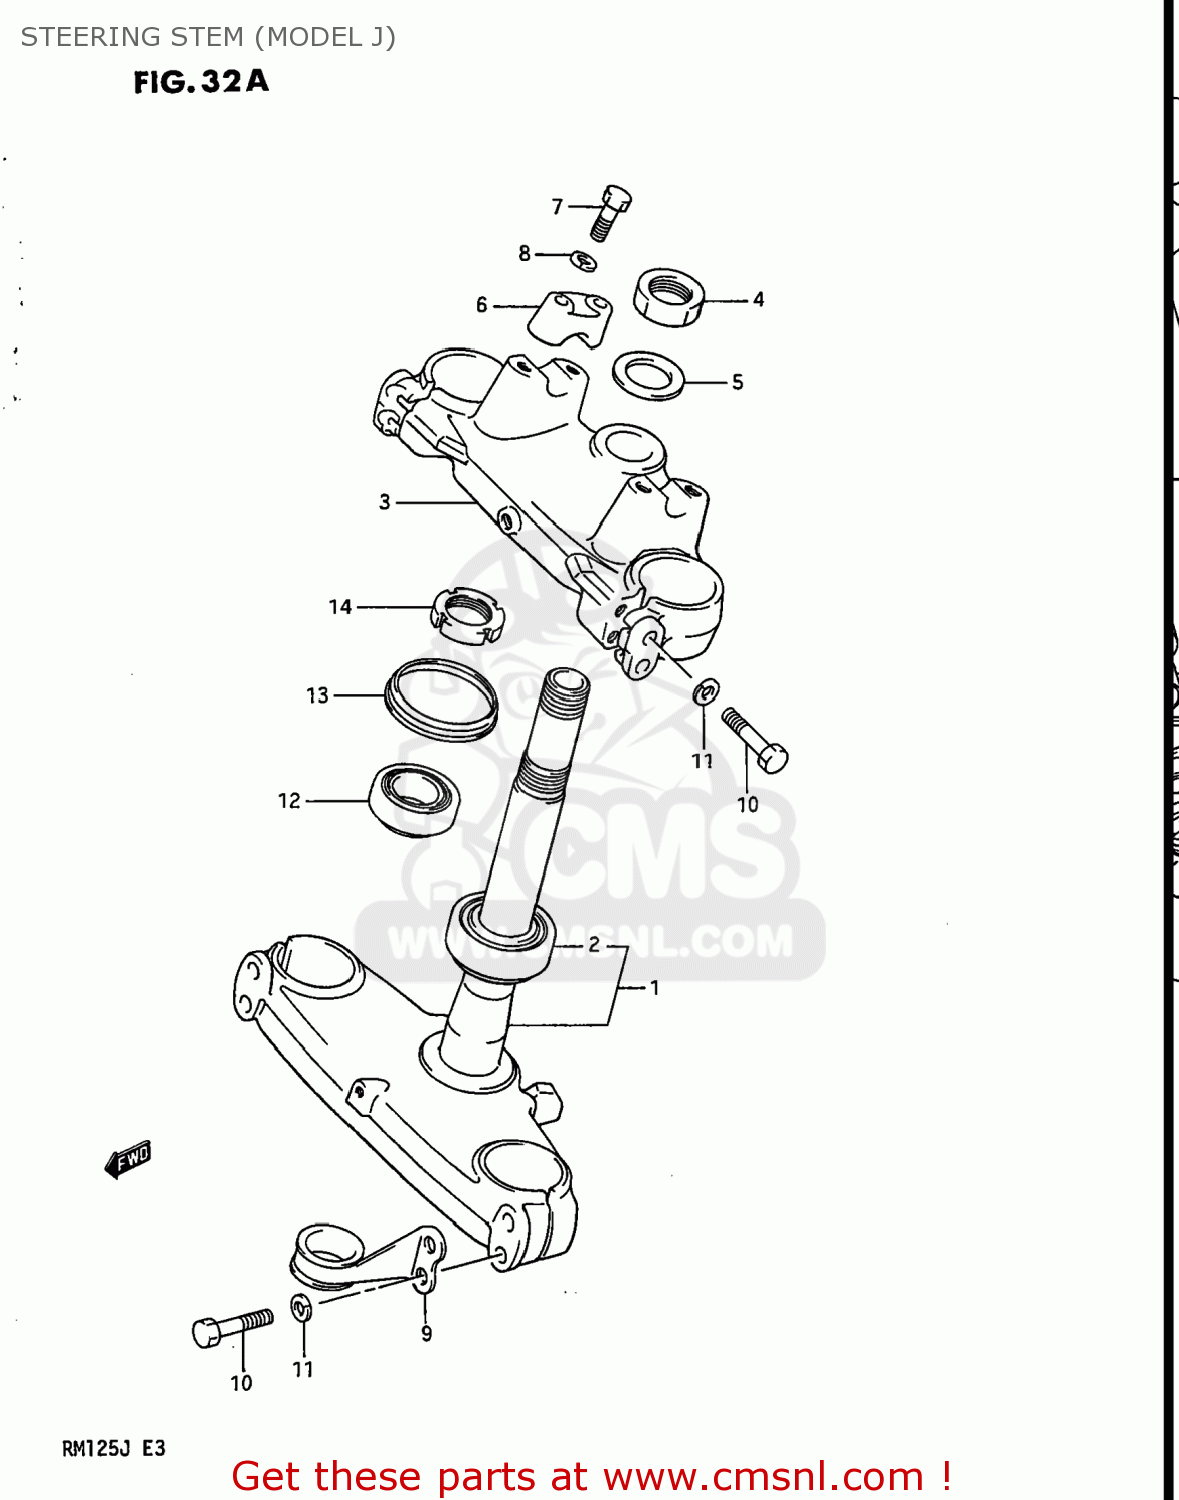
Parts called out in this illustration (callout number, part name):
1	STEM,STEERING
2	BEARING
3	HEAD,STEERING STEM
4	NUT,STEERING STEM
5	WASHER
6	HOLDER,HANDLEBAR
7	BOLT
8	LOCK WASHER
9	CLIP
10	BOLT 8X40
11	LOCK WASHER
12	TAPER,ROLLER BEARING
13	SEAL,STEERING UPR DUST
14	NUT,STEERING STEM
